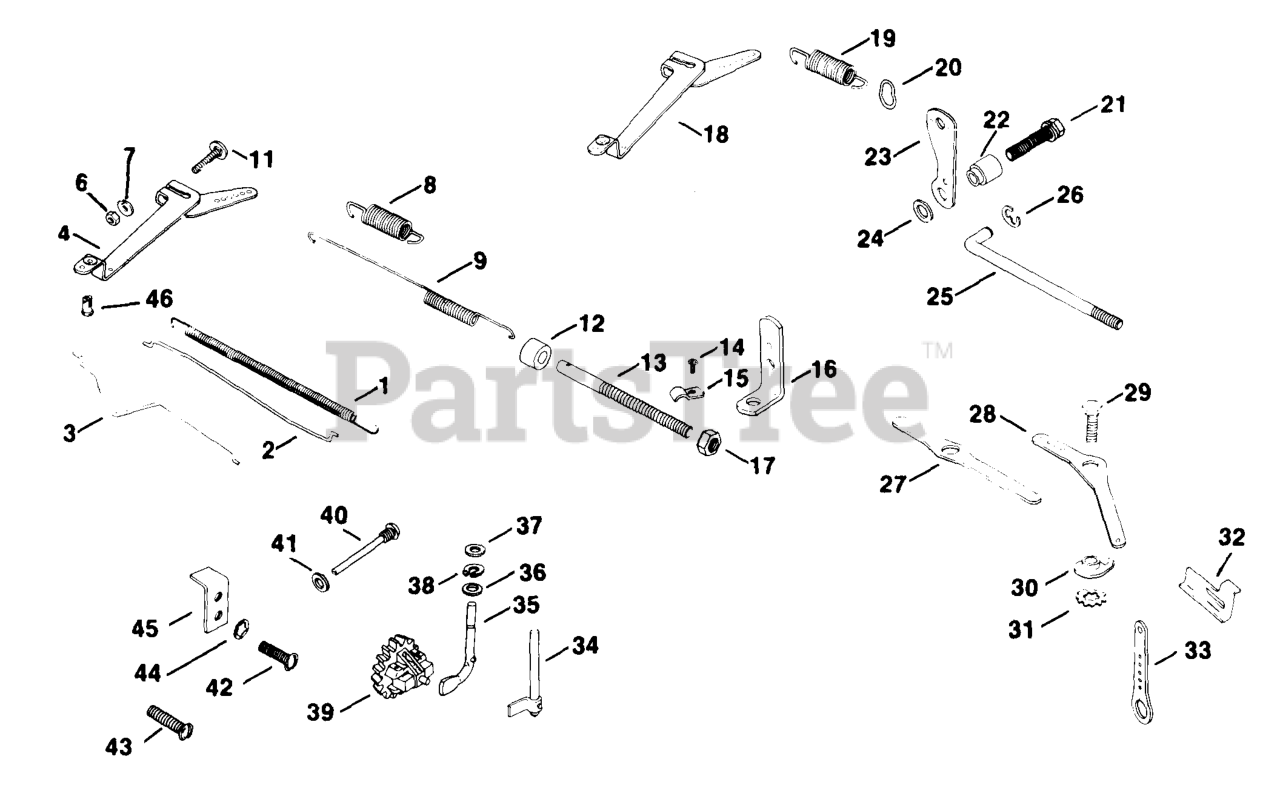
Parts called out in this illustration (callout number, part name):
3	KIT - USE 52 755 64
6	NUT, 1/4-20 GRADE 2 USE 25 100 20-S
7	WASHER, FLAT 1/4"
9	SPRING - (#DSC)
11	BOLT, RD HD SQ NCK 1/4-20X1"
14	Screw, H.C. 10-24x7/16
18	KIT - USE 52 755 64
27	LEVER - DISCONTINUED
29	SCREW, CAP HD 1/4-20x5/8"
31	WASHER,INT EXT TOOTH LOCK 1/4"
35	SHAFT - (#DSC)
36	WASHER, FLAT 1/4"
37	WASHER, FLAT 1/4" (O.D. 1/2")
39	KIT, GOVERNOR GEAR
46	BUSHING USE 25 158 08-S
